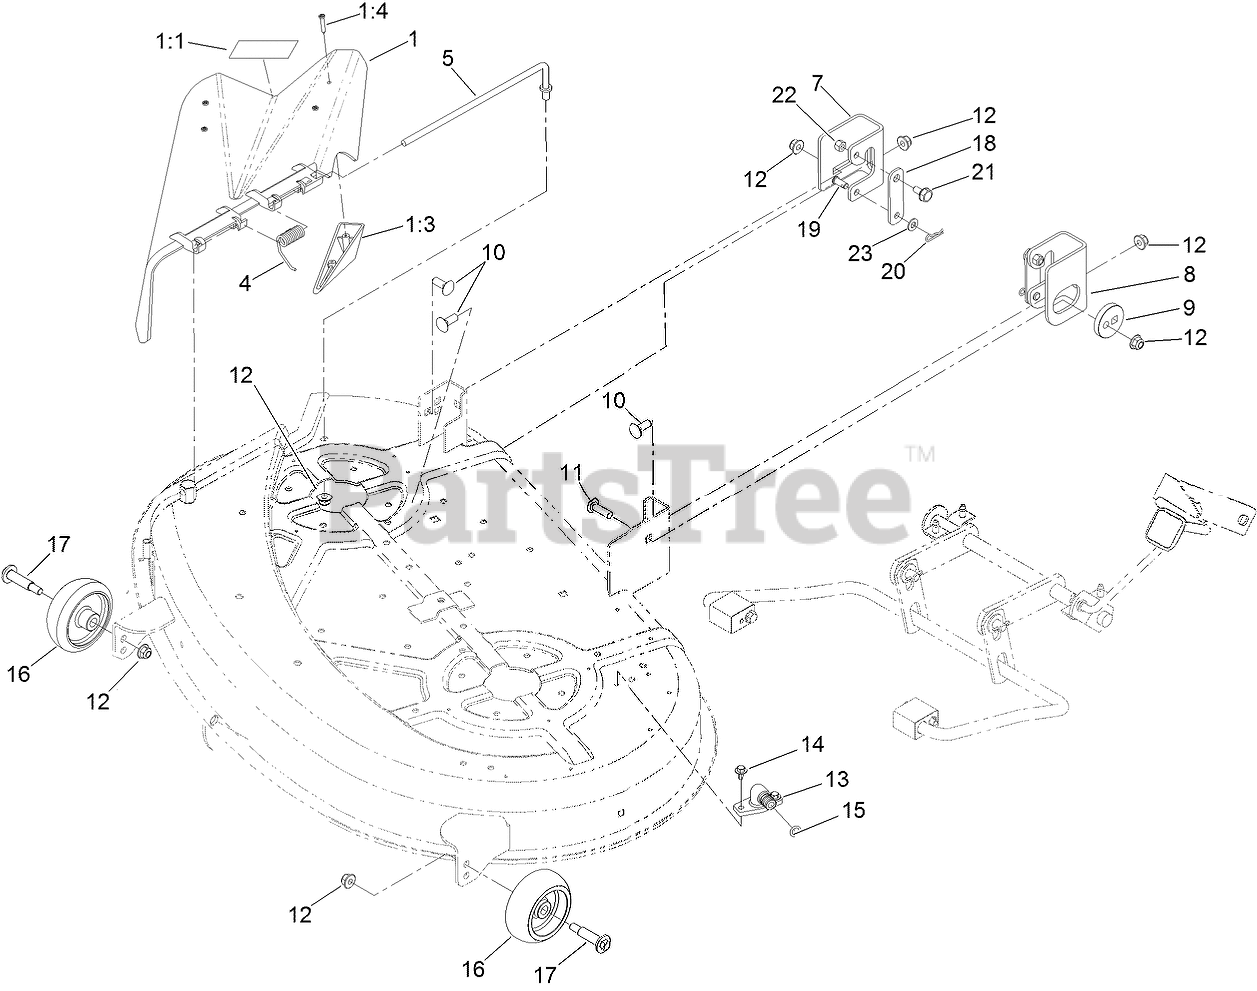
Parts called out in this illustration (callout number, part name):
1	DEFLECTOR ASM
1:1	DECAL-DANGER
1:3	KICKER
1:4	SCREW-PPH
4	SPRING-TORSION
5	ROD-PIVOT
7	BRACKET-HANGER, RH
8	BRACKET-HANGER, LH
9	ECCENTRIC
10	BOLT-CARR
11	SCREW-CARR
12	NUT-HF, NI
13	FITTING-WASHOUT
14	SCREW-HHFTF
15	O-RING
16	WHEEL-GAGE
17	SCREW-SHOULDER, HWH
18	BRACKET-DECK SUPPORT
19	PIN-CLEVIS
20	PIN-COTTER
21	BOLT-SHOULDER
22	NUT-LOCK, NI
23	WASHER-PLAIN
